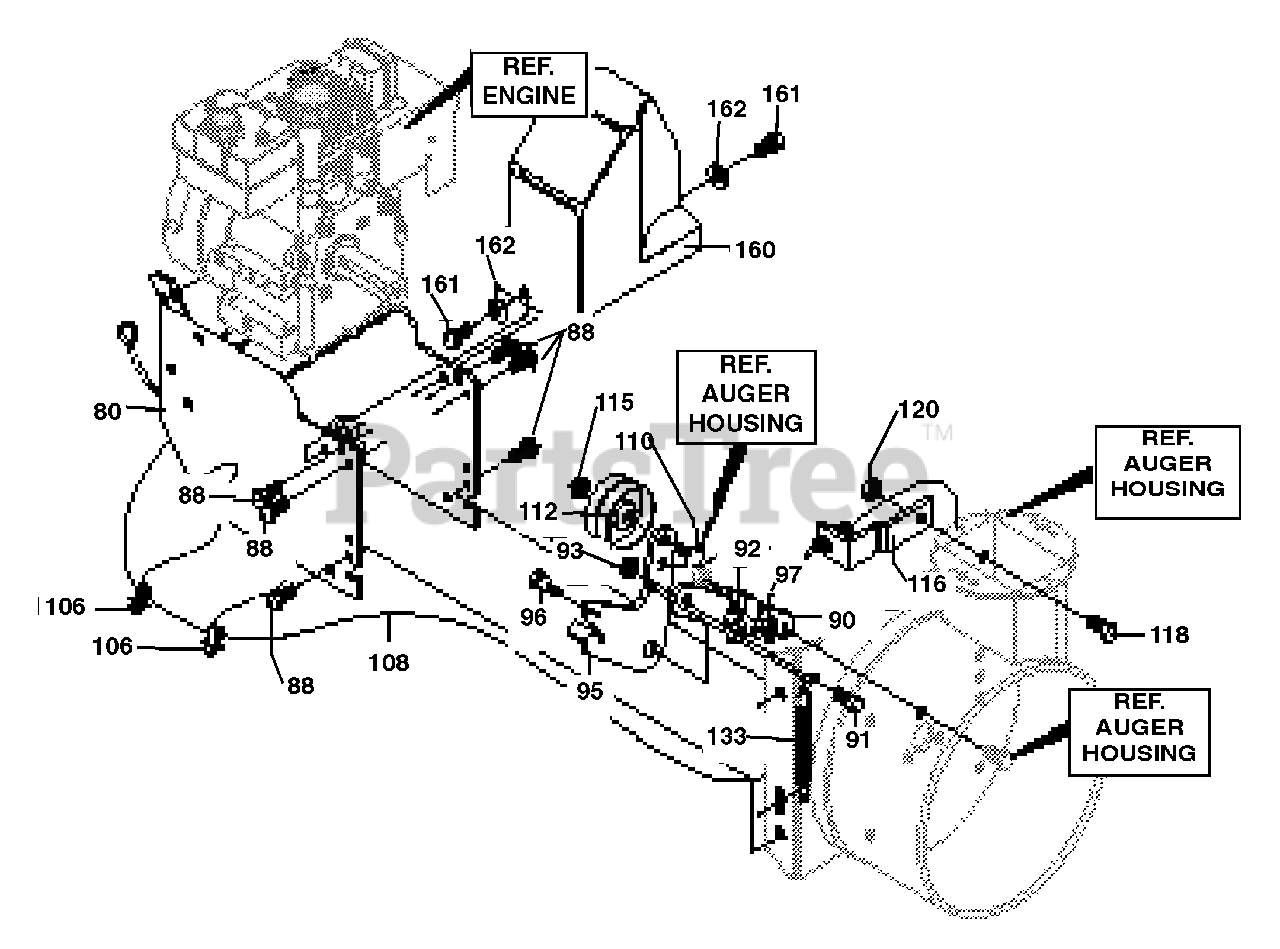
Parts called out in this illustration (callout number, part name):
80	Frame Assy
88	Screw, 5/16-18 x .75
90	Plate-Clutch Arm
91	Screw, 3/8-16 x .75
92	Washer, Regsptlk
93	Nut, 3/8-16
95	Arm-Clutch
96	Bolt, .497 x .138 3/8-16
97	Nut, 3/8-16 Reghexctrlk
106	Clip, Cable
108	Cable, Auger Clutch Ctrl
110	Screw, 3/8-16 x 1.25
112	Pulley, Idler
115	Nut, 3/8-16 Hexctrtlkjam
116	Bracket, Compact Cable
118	Screw, 3/8-16 x 1.25
120	Nut, 3/8-16 Reghexctrlk
133	Spring, Idler
160	Cover, Belt w/Storage
161	Screw, 1/4-20 x .63
162	Flatwasher, .281 x .63 x .065
